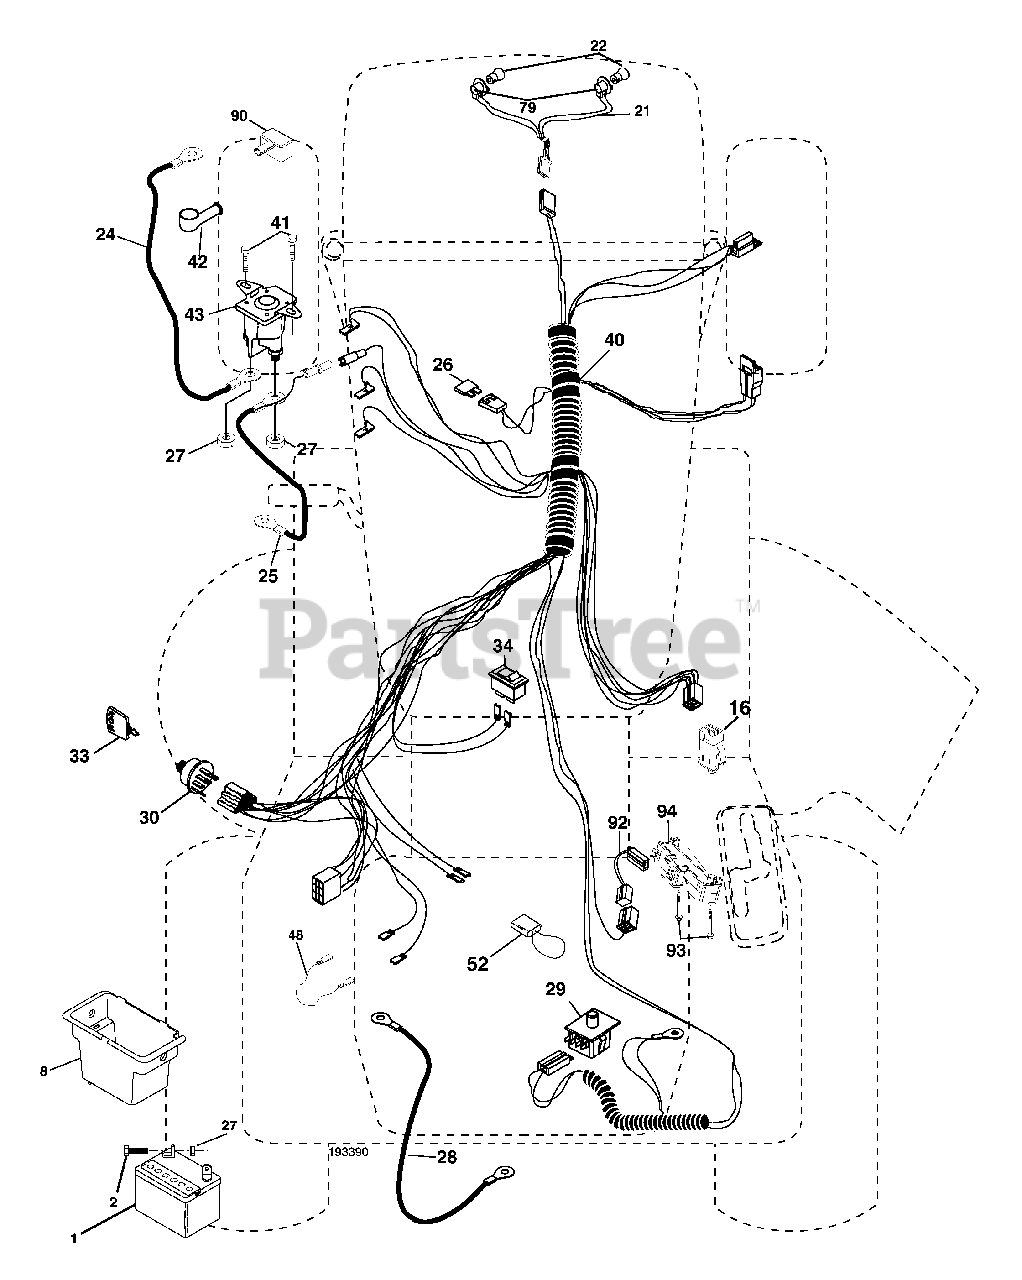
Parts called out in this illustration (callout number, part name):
2	Bolt Hex Hd 1/4-20 unc x 3/4
8	Box Battery
16	Switch Interlock
21	Harness Socket Light
22	Bulb, Light # 1156
24	Cable Battery
25	Cable Battery
26	Fuse
27	Nut Keps Hex 1/4-20 unc
28	Cable Ground
29	Switch Seat
30	Switch Ign
33	Key Ign Molded Generic
34	Switch Light/Reset
40	Harness Ign
41	Bolt Fin Hex 1/4-20 unc x 1/2
42	Cover Terminal Red
43	Solenoid
48	Adaptor Ameter
52	Protection Loop
79	Socket Asm Bulb Twistlock
90	Cover Terminal
92	Harness Pigtail Reverse Switch
93	Screw Plastite 10-14 x 2.0
94	Module Revers ROS
